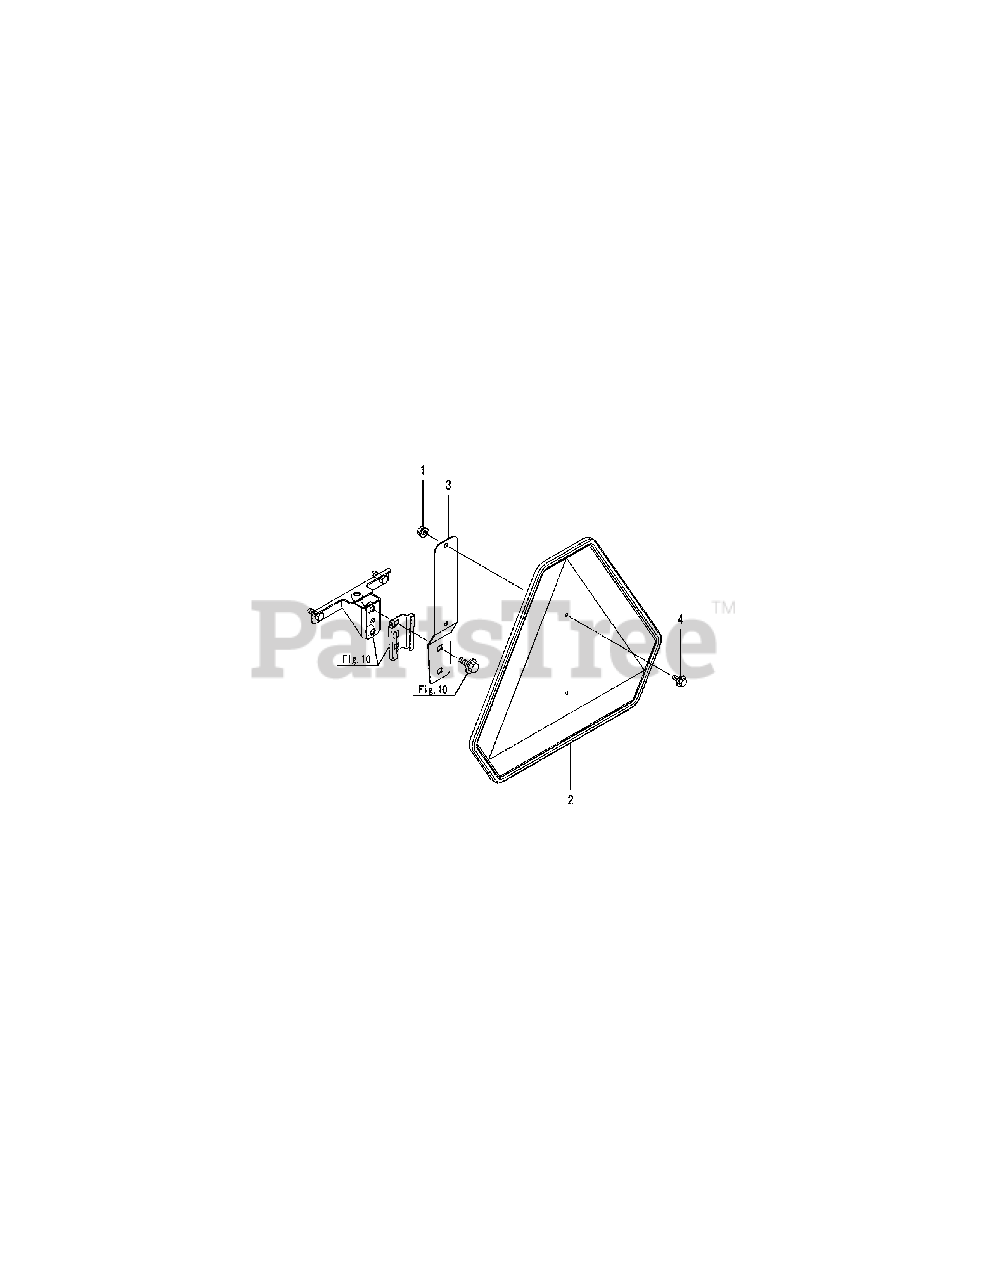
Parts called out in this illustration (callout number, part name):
1	NUT W/WASHER 6
2	EMBLEM, SMV ASSEMBLEY
4	BOLT M 6X 16 PLATED
